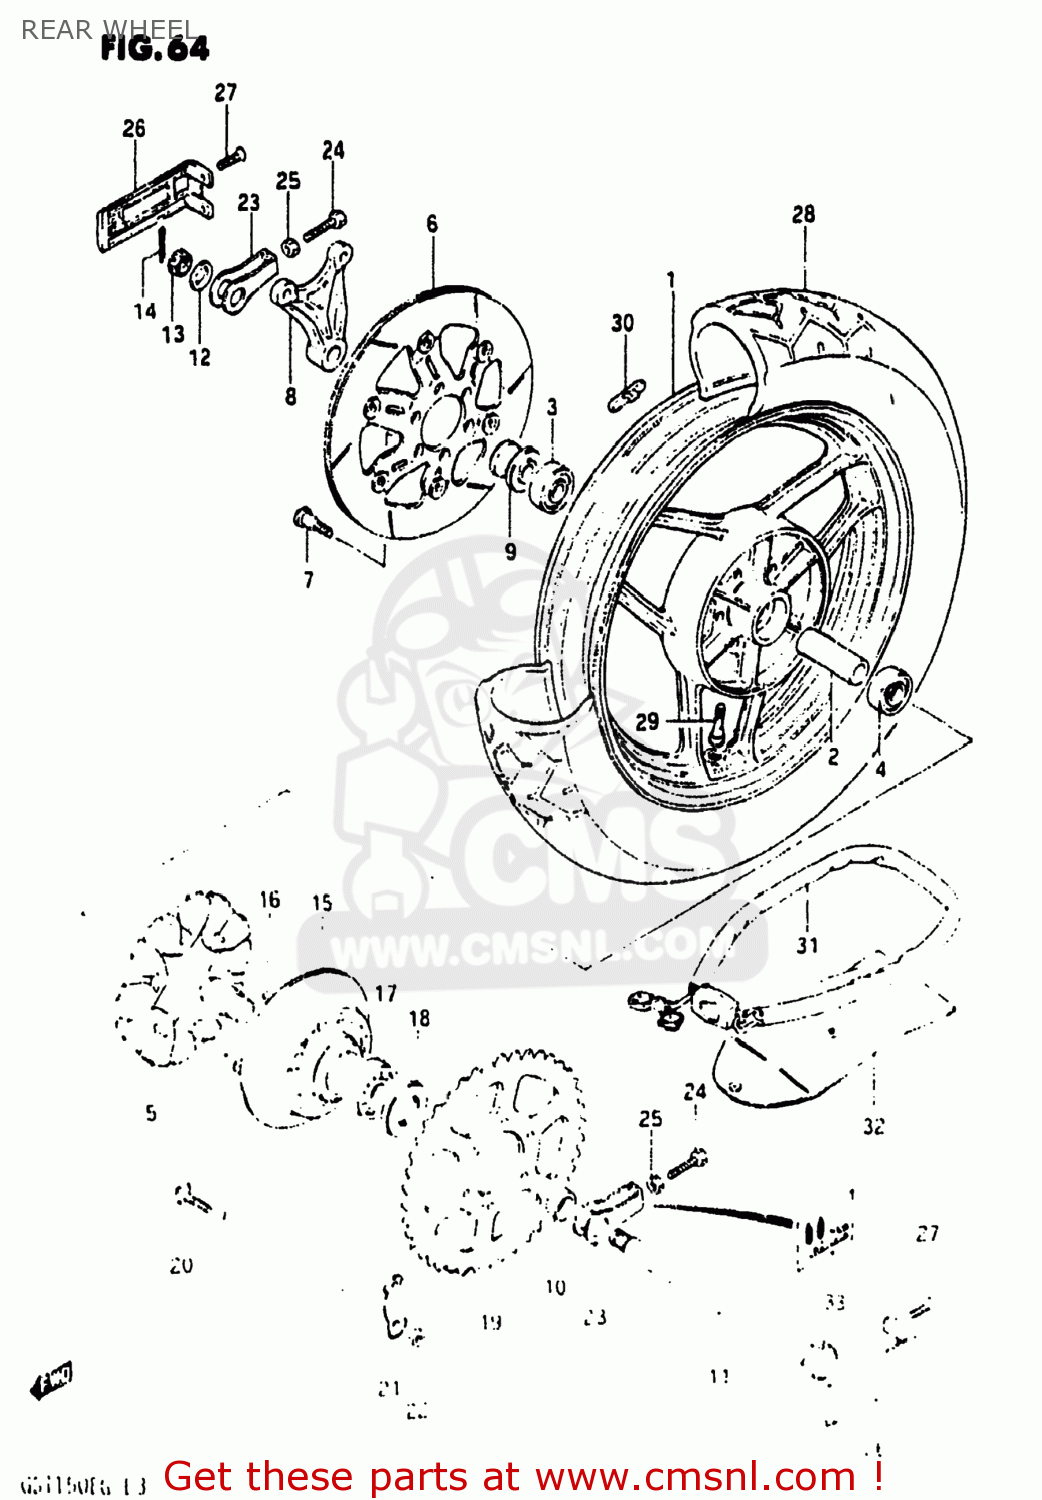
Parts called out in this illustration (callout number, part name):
1	CASTING WHEEL,REAR 3.00
2	SPACER (20.5X28X83)
3	BEARING WHEEL REAR(20X47X14)
4	BEARING, LH
5	ABSORBER,REAR HUB SHOCK
6	DISC,RR BRAKE
7	BOLT
8	BRACKET,RR,CALIPER
9	SPACER,RR AXLE,R
10	SPACER (20X33X13.3)
11	AXLE,REAR
12	WASHER (19X32X2.6)
13	NUT 18MM
14	PIN,COTTER
15	DRUM,REAR SPROCKET MOUNT
16	SPACER,REAR HUB BEARING
17	BEARING
18	SEAL,OIL(33X62X7)
19	SPROCKET,REAR
20	BOLT(10X35.5)
21	WASHER
22	NUT
23	ADJUSTER CHAIN
24	BOLT 8X50
25	NUT
26	COVER,CHAIN ADJUSTER
27	SCREW 5X16
28	TIRE
29	VALVE,TIRE
30	BALANCER,WHEEL
31	CHAIN LOCK ASSY
32	BAG,CHAIN LOCK
33	LABEL,CHAIN WEAR INDICATOR
